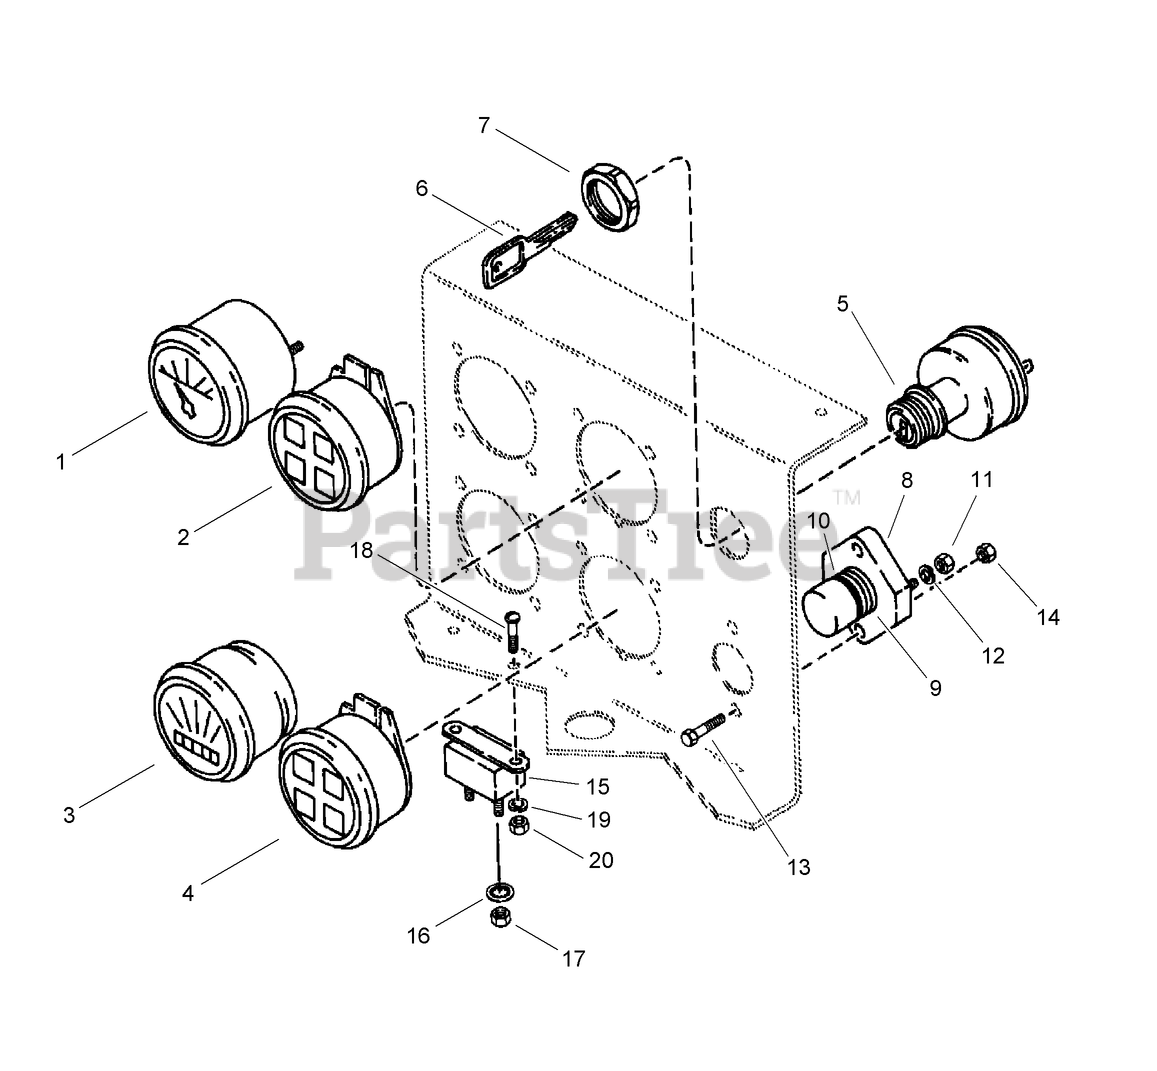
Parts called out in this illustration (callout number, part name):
1	GAUGE - Fuel
2	GAUGE - Warning
3	GAUGE - Hour
4	CLUSTER - Hyd w/Neutral Indicator
4	ASSEMBLY - Ignition Switch (Includes Items 5, 6 and 7)
5	SWITCH - Ignition
6	KEY - Set of Two, Ignition
7	NUT - Hex, Special, Key Switch Mounting
7	SWITCH-STARTER
8	SWITCH - Heater
9	SPRING - Heater Switch
10	O-RING - Switch
11	NUT - Hex, 5/16 inch NF
12	WASHER-Lock, 5/16 inch
14	NUT-Prev Trq 1/4 GRC PHC Direct
15	BREAKER - Circuit, 25 Amp
16	WASHER - Ext Tooth Lock 0.190 in ZND
17	NUT - Hex, #10-32 UNF, 303 Stainless Steel
18	SCREW - Machine, 10 - 32 x 3/4 Slotted Pan Head
19	WASHER - Spring Lock, Split Type, No. 10
20	NUT - Hex, #10-32 UNF, 303 Stainless Steel
